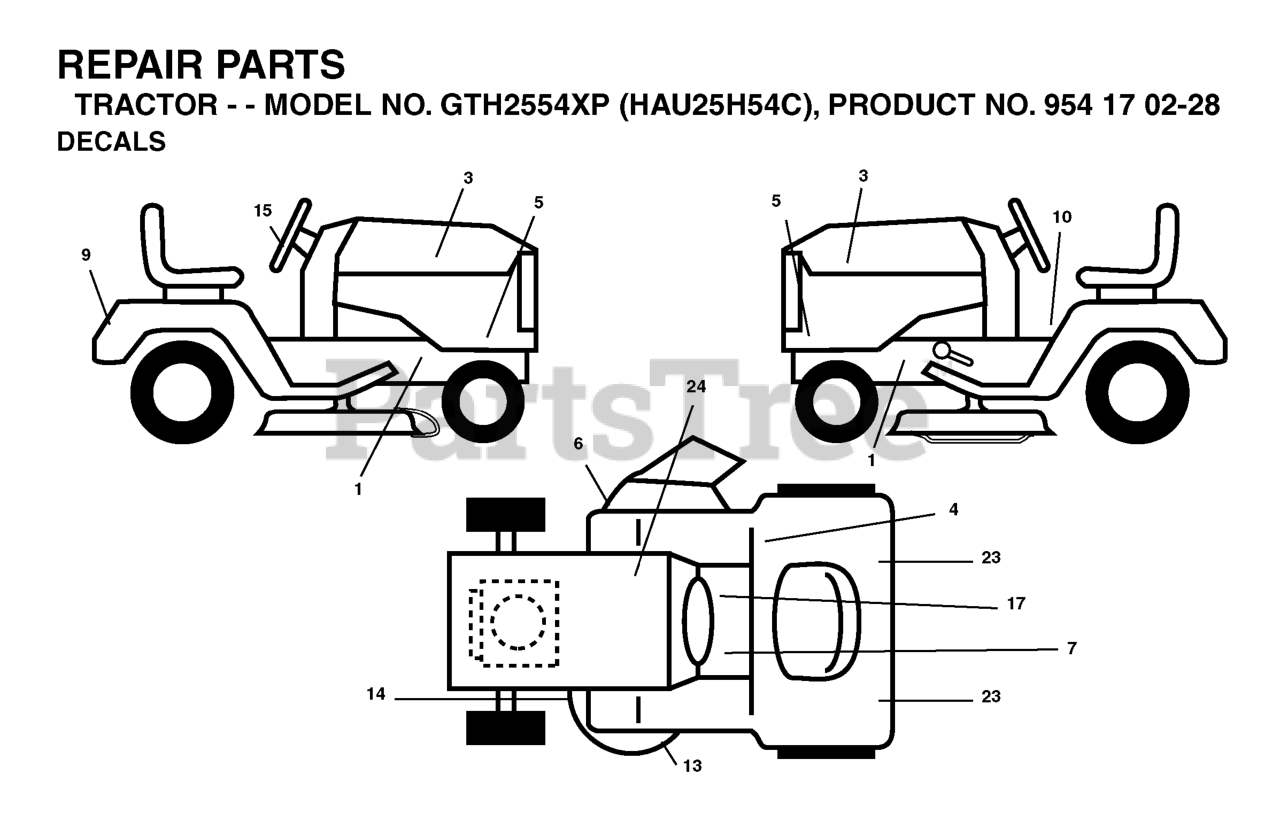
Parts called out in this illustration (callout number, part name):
3	DECAL.HOOD.HUSQVARNA.INTERNATI
4	DECAL
6	DECAL.INTERNATIONL.CUTFINGER
7	DECAL
10	DECAL READ OWNER'S MAN SYMS
13	DECAL.SCHEMATIC.DECK
14	DECAL CLUTCH/BRAKE
15	DECAL.STEERING.HUSQ.BLUE
17	DECAL PARK BRAKE
23	REFLECTOR-TAIL YT
24	DECAL BTRY SYMBOLS
